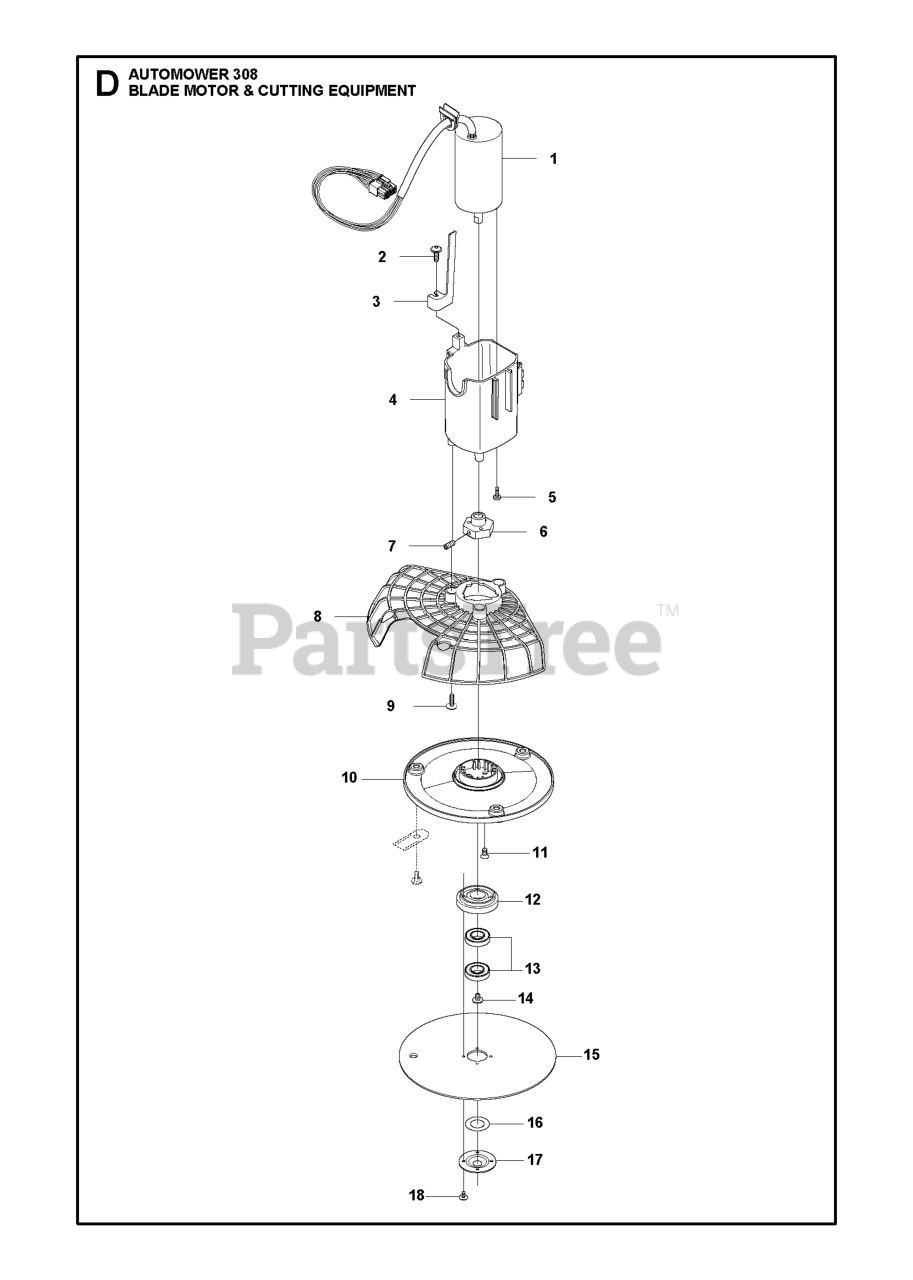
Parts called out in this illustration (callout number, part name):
2	SCREW 14MM
3	HEIGHT INDICATOR
5	SCREW ITXPANM M4X12 8.8 ZP-BC
7	SCREW IHSETM M5X10 8.8 ZP-BC
9	SCREW 14MM
11	SCREW
13	BALL BEARING BALL BEARING 535
17	COVER SKID PLATE
18	SCREW SILVER 10MM
